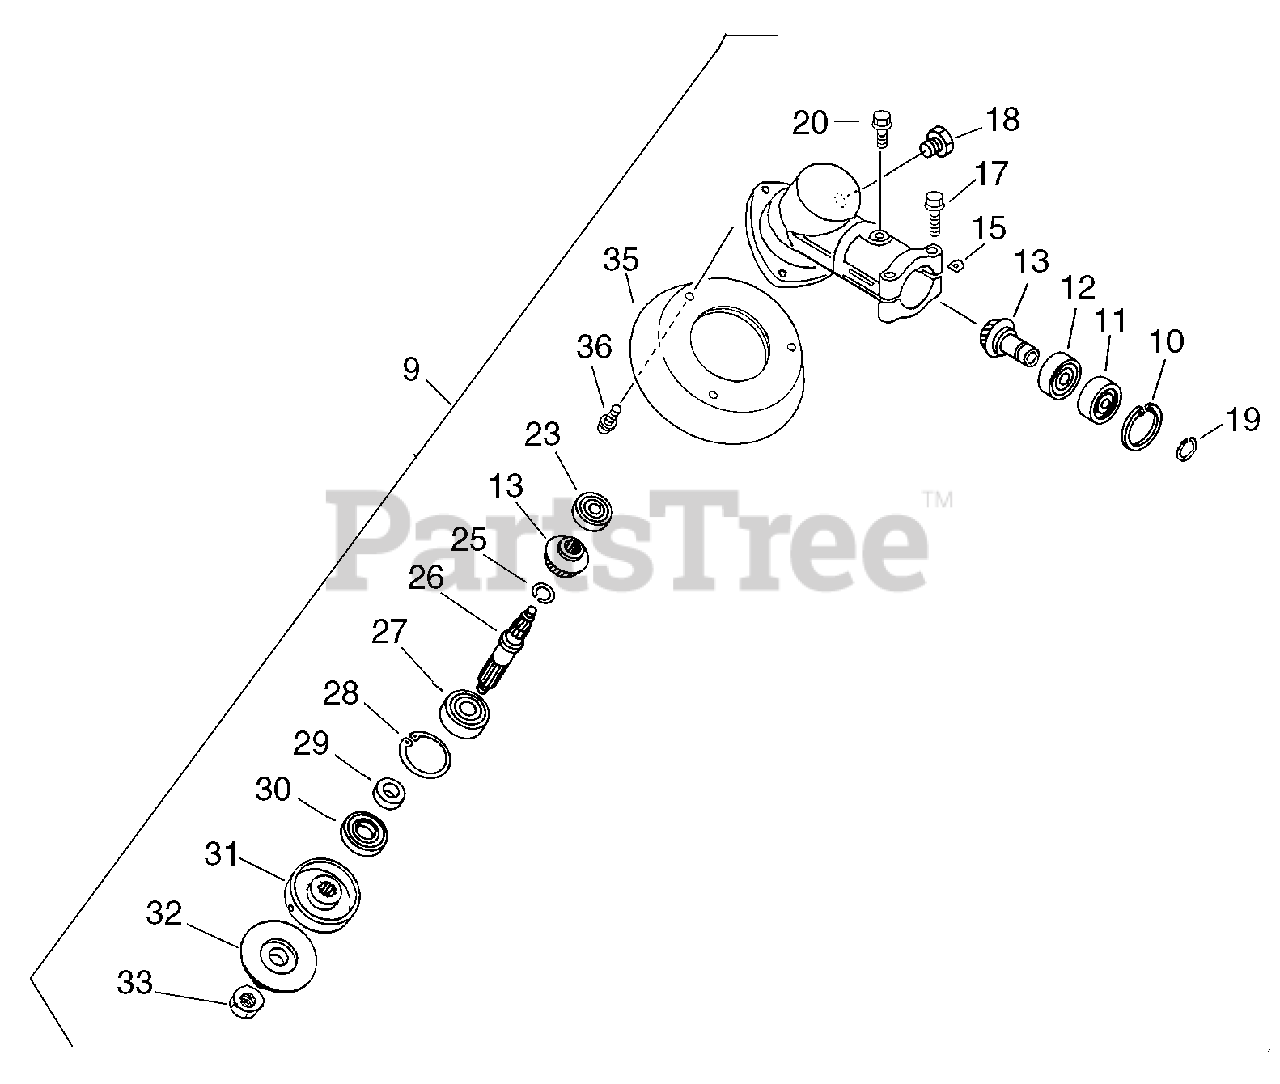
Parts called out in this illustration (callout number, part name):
9	GEAR CASE ASSY
10	RING, RETAINING - 28
11	BEARING, BALL - 6001
12	BEARING, BALL - 6001C3
13	GEAR SET
15	D-WASHER
17	BOLT - 5X30
18	BOLT - 8X8
19	RING, RETAINING - 12
23	BEARING, BALL - 6000
25	RING, RETAINING - 12
26	GEAR - SHAFT
27	BEARING, BALL - 6201
28	RING, RETAINING - 32
30	SEAL, OIL
31	ADAPTOR, BLADE - UPPER
32	ADAPTOR, BLADE - LOWER
35	COVER, GEAR CASE
36	SCREW - 5X22
